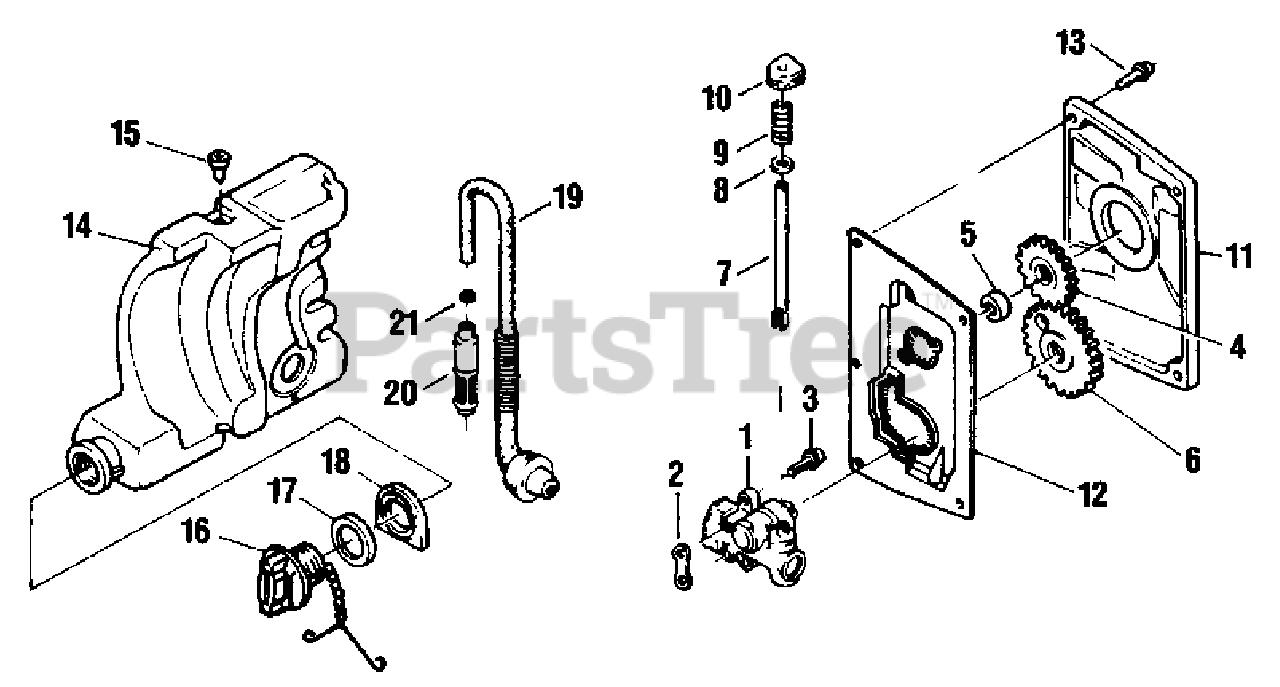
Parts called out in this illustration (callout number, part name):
1	OIL PUMP ASSY
2	GASKET, OIL PUMP
3	SCREW - 4X14
4	GEAR - PINION
6	GEAR
7	SHAFT, OIL PUMP
8	WASHER - 4
11	COVER, PUMP
12	COVER, DUST
13	SCREW - 4X14
14	TANK, OIL
15	VALVE, OIL TANK
16	CAP, OIL
17	GASKET, CAP
18	TANK, OIL
19	TUBE, OIL
20	CLIP
21	CLIP
